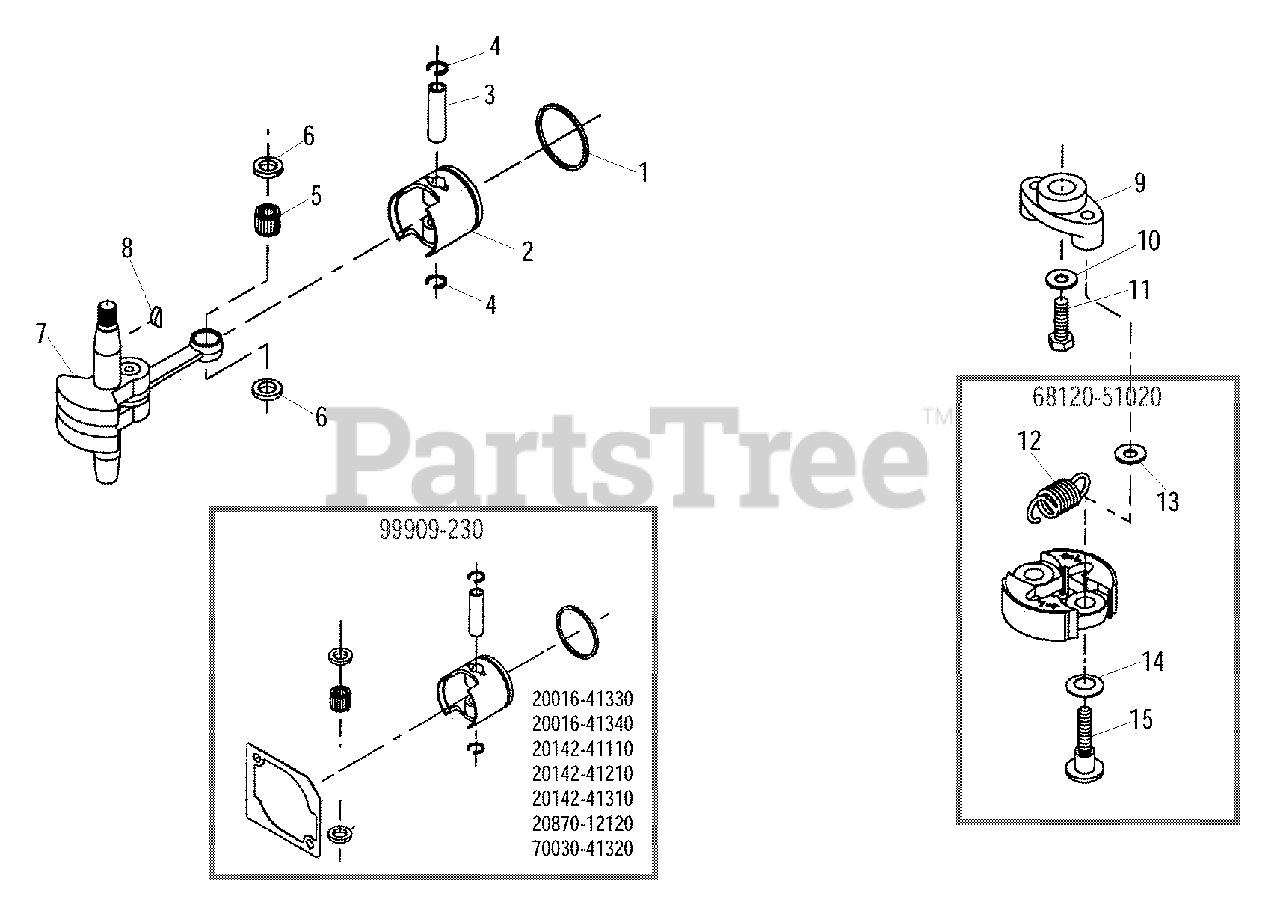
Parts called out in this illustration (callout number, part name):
1	RING, PISTON
2	PISTON
3	PIN, PISTON
4	RING, SNAP
5	BEARING, NEEDLE
6	WASHER, THRUST
7	CRANKSHAFT ASSY
8	KEY, WOODRUFF 3×10
9	HUB, CLUTCH
10	WASHER 6 MM
11	BOLT M6×18
12	SPRING, CLUTCH
13	WASHER 6 MM
14	WASHER, SPRING
15	BOLT
20870-12120	GASKET, CYLINDER
68120-51020	CLUTCH SHOE ASSY
99909-230	PISTON ASSY
